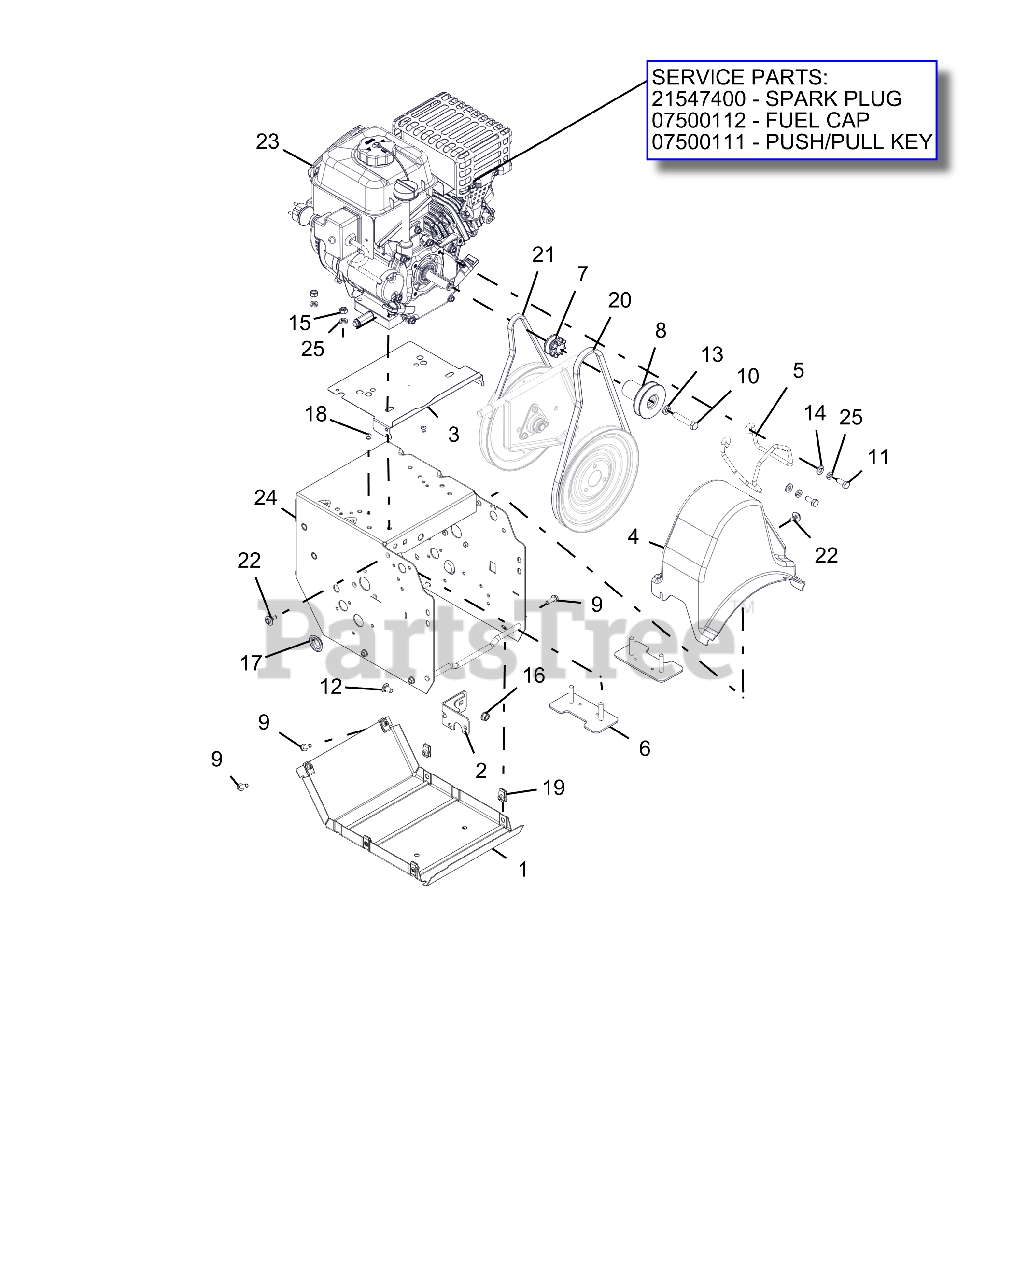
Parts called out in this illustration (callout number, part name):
1	COVER, BOTTOM
2	WELDMENT, FRAME BRACKET
3	BAFFLE,ENGINE,SMALL BLOCK
4	COVER, COMPACT BELT
5	FINGER, BELT
6	STRAP, ENGINE BOLT-WELDMENT
7	SHEAVE, TRACTION
8	SHEAVE,AUGER 3/4" PM
9	BLT-HEX .25-20X.75 HWH YZ GR5
10	BLT-HEX .38-24X2.0 YWZC
11	BLT-HEX .31-24X.75 YWZC GR5
12	@BLT-RHDSSQNK .31-18X.62 G5YZ
13	WSHR-LK .375X.115 HVY YWZC
14	@WSHR-FL-STL.344X.688X.065YWZC
15	@NUT-HEX .31-18 YWZC
16	@NUT-LK-TOP-FLG .31-18 YWZC
17	PLUG, HOLE - 1.00" FLEXTEMP
18	RVT-POP .187 YZ
19	NUT-RTNR .25-20X.56
20	V-BELT, HA-RAW EDGE
21	V-BELT, 3L-WRAPPED
22	SCR-TAP .25-20X.5 CAPTIVE
23	ENGINE, SNO-TEK 136 240V
23	PLUG, SPARK
23	CAP, FUEL TANK BLACK
23	KEY, PUSH/PULL LCT (2/PACKAGE)
24	WELDMENT,FRAME 920
25	WSHR-LK .312X.097 HVY YWZC
